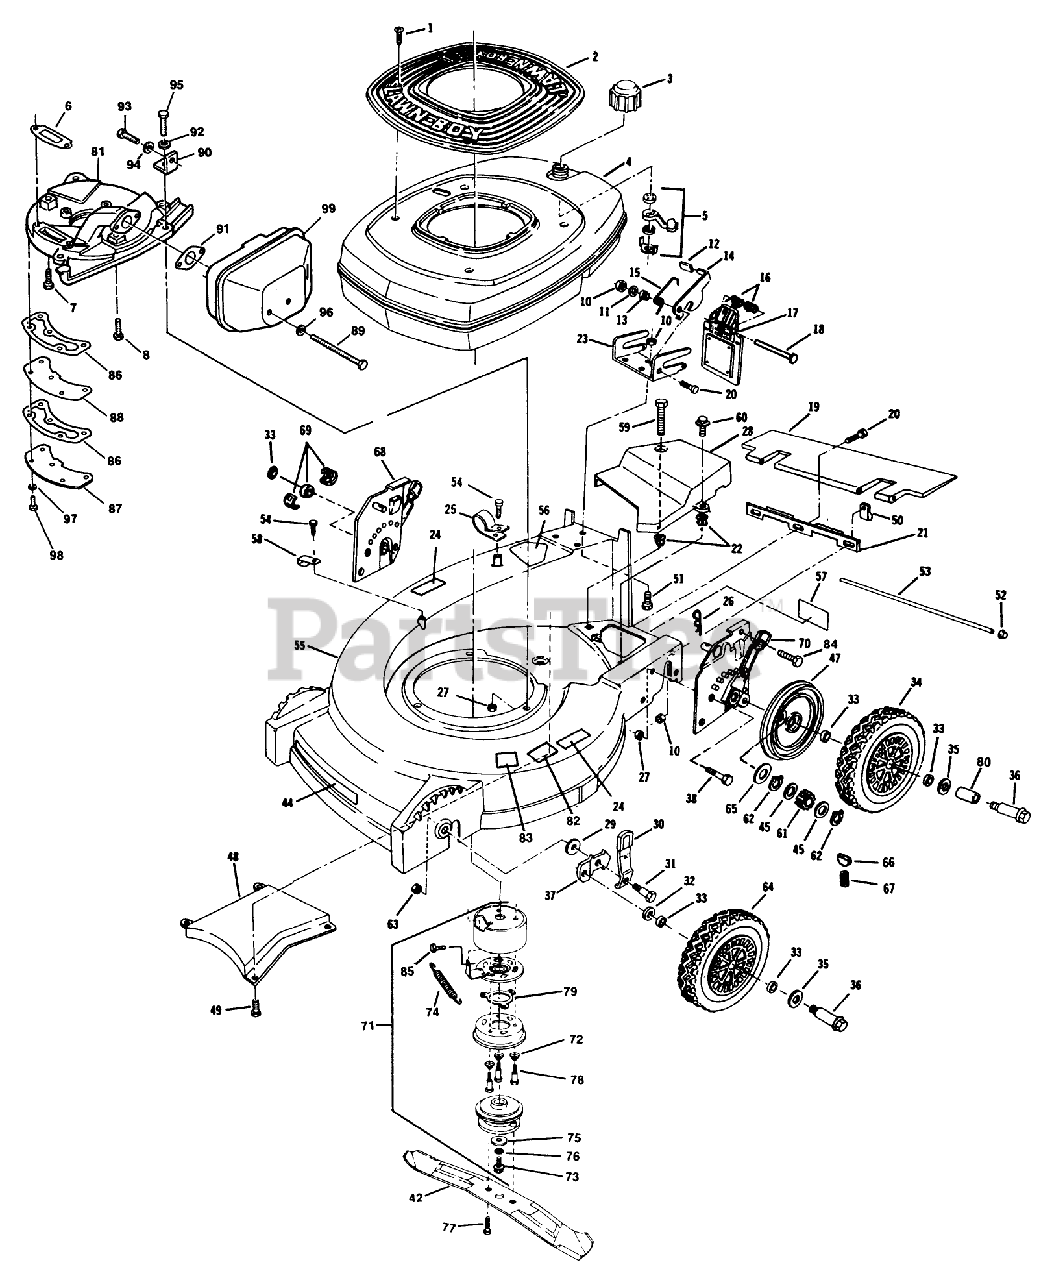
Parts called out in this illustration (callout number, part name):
1	SCREW - SELF TAPPING
3	FUEL CAP & INSERT
4	SHROUD TANK&VALVE
5	SHUT-OFF VALVE S
8	SCREW V
9	SCREW-HH
10	LOCKNUT E
15	SPRING
16	SPRING ASOC
18	ROD (RB&W)
19	T/SHIELD SM&P
26	HAIR PIN
27	NUT-LOCK F
29	WASHER
31	BOLT
32	WASHER WROUGHT
33	WASHER
35	SPACER
36	BOLT WHEEL
45	SPACER/GR ALGHNY
48	BAFFLE CHUTE PL
54	SCREW LAWRENCE
60	SCREW
61	PINION BROCKWAY
62	RET RING
63	LOCKNUT
64	WHEEL&TIRE 8" TRI
65	THRUST WASHER
66	KEY
67	SPRING
69	REAR AXLE BEARING
72	Spring
74	SPRING
75	WASHER
77	SCREW SEMS
78	SCREW,SHOULDER SM
79	GASKET S
82	PAD FOOT
86	GASKET S
87	COVER HIP
91	GASKET S
93	SCREW-SEMS
94	WASHER
95	BOLT F
98	SCREW - USE 137-3042
